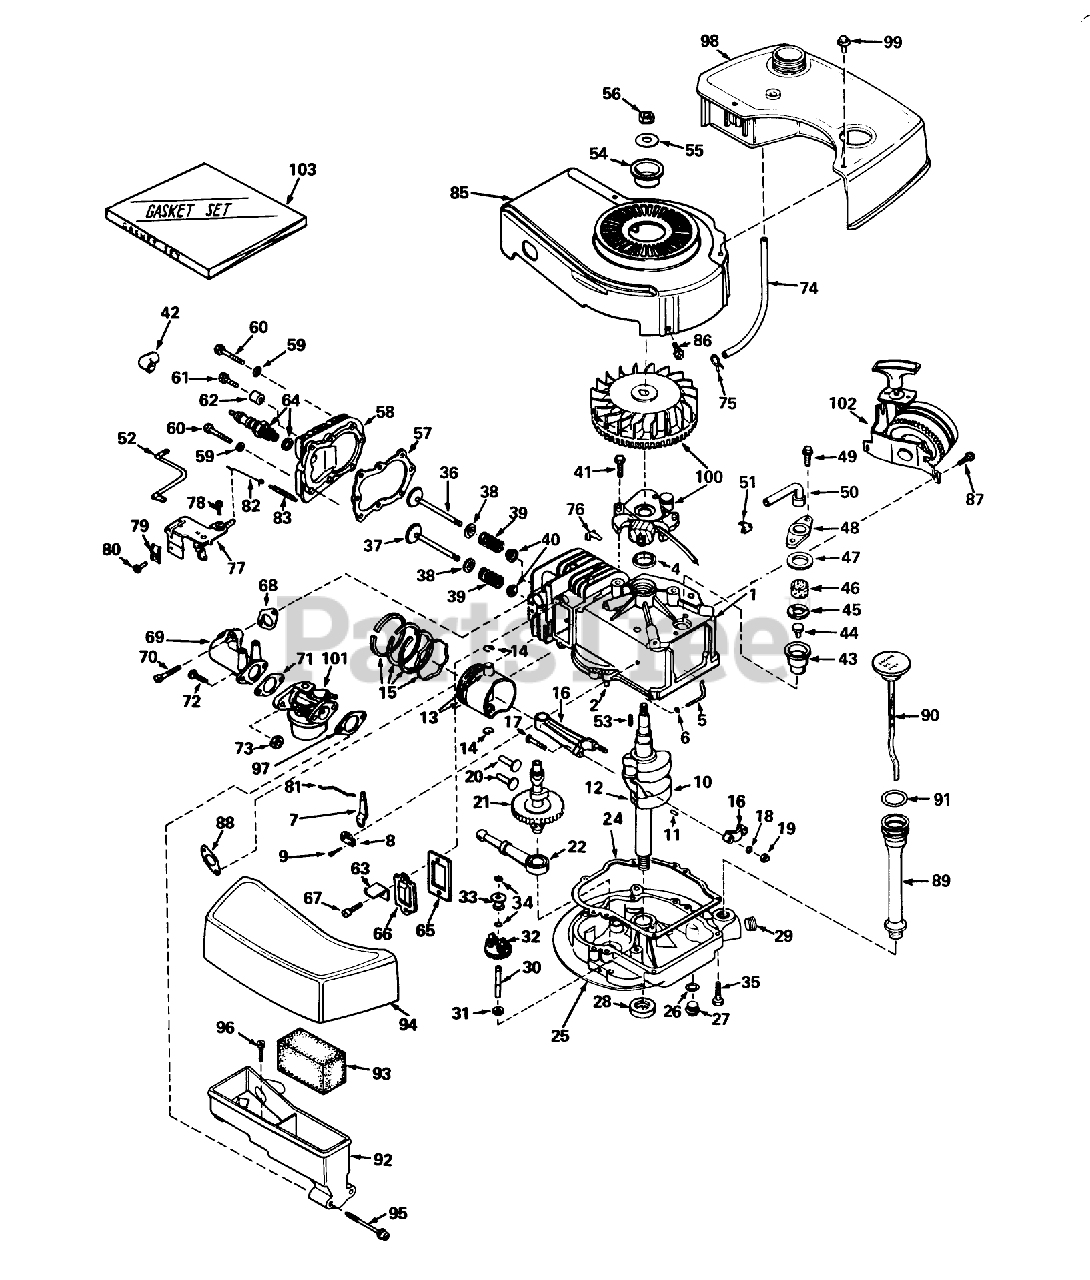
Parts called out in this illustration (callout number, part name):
1	Cylinder Assy. (Incl. Ref. #2, 4 105)
2	Pin-Dowel
4	OIL SEAL
5	Rod, Governor (Incl. No. 36)
6	Washer-Flat
7	Governor Lever
8	Clamp-Lever, Governor
9	Screw
10	Crankshaft Assembly (Incl. Nos. 12 13)
11	Pin, Groove
12	Gear, Crankshaft
13	Piston Pin Assembly (Incl. 2 of No. 14) (.010 Oversize)
13	Piston Pin Assembly (Incl. 2 of No. 14) (.020 Oversize)
14	Ring-Retaining, Piston Pin
15	Ring Set Piston (Std.)
15	Ring Set Piston (.010 Oversize)
15	Ring Set Piston (.020 Oversize)
16	Rod Assy., Connecting (Incl. Ref. #17)
17	Bolt, Connecting
18	Washer
19	LOCKNUT
20	Lifter-Valve
21	Camshaft
22	Oil Pump ASM
24	Gasket, Mounting
25	Filter, Air Cleaner
26	Gasket-Oil Drain
27	Plug Oil Drain
28	Seal Oil
29	Plug Oil Drain
30	Shaft-Governor
31	Washer-Flat
32	Governor Gear ASM
33	Spool-Governor
34	Ring-Retaining
35	Screw (1/4-20 x 1-1/4)
36	Valve, Intake (Incl. Ref. #38, 39 40) (Std.)
36	Valve, Exhaust (1/32" Oversize) (Incl. Nos. 8, 9 10)
37	Valve, Exhaust (Standard) (Incl. Nos. 8, 9 10)
37	Valve, Exhaust (1/32" Oversize) (Incl. Nos. 8, 9 10)
38	Cap-Upper Valve Spring
39	Spring-Valve
40	Cap-Valve, Spring
41	Screw
42	Cover-Spark Plug
43	Body Breather Tube
44	Valve Check
45	2000A37 WIZARD ROTA
46	Element-Breather
47	Gasket-Breather
48	Cover Breather
49	Screw, Hex Hd. w/Conical
50	Tube, Breaker
51	Clip, Breather
52	Wire, Ground
53	Key Flywheel
55	Washer
56	Hex Nut
57	63573 GIL 42 SNWTHW
58	Head Cylinder
59	Washer
60	Screw
61	Screw Hex Hd. Cap
62	Space
63	Retainer Clip
64	Plug, Spark (J17LM or equiv.)
65	Gasket-Breather
66	Cover-Valve
67	Screw
68	Gasket, Intake
69	Pipe, Intake
70	Screw (1/4-20 x 1)
71	Gasket
73	Nut and Lock Washer (1/4-28)
74	Line, Fuel
75	Clamp-Line, Fuel
76	Clip-Wire
77	Control Assy., Speed
78	Screw (10-24 x 3/4)
79	Conduit
80	Screw (10-32 x 3/8)
81	Link Governor
82	Link Governor Spring
83	Spring Governor
85	Housing, Blower
86	Screw
87	Screw (1/4-20 x 1/2)
88	Gasket Exhaust
89	Tube, Oil Filler
90	Dipstick, OiI (Incl. No. 91)
91	O-Ring
92	Body Air Cleaner
93	Filer, Air
94	Cove, Air Cleaner
95	Screw Fil Hd.
96	Screw, Hex Hd.
97	Gasket-Air Cleaner
98	Tank Fuel
99	Screw (10-32 x 35/64)
100	Magneto
101	Carburetor
102	Starter, Side Mount
103	53024/VAR.16HP O/P
